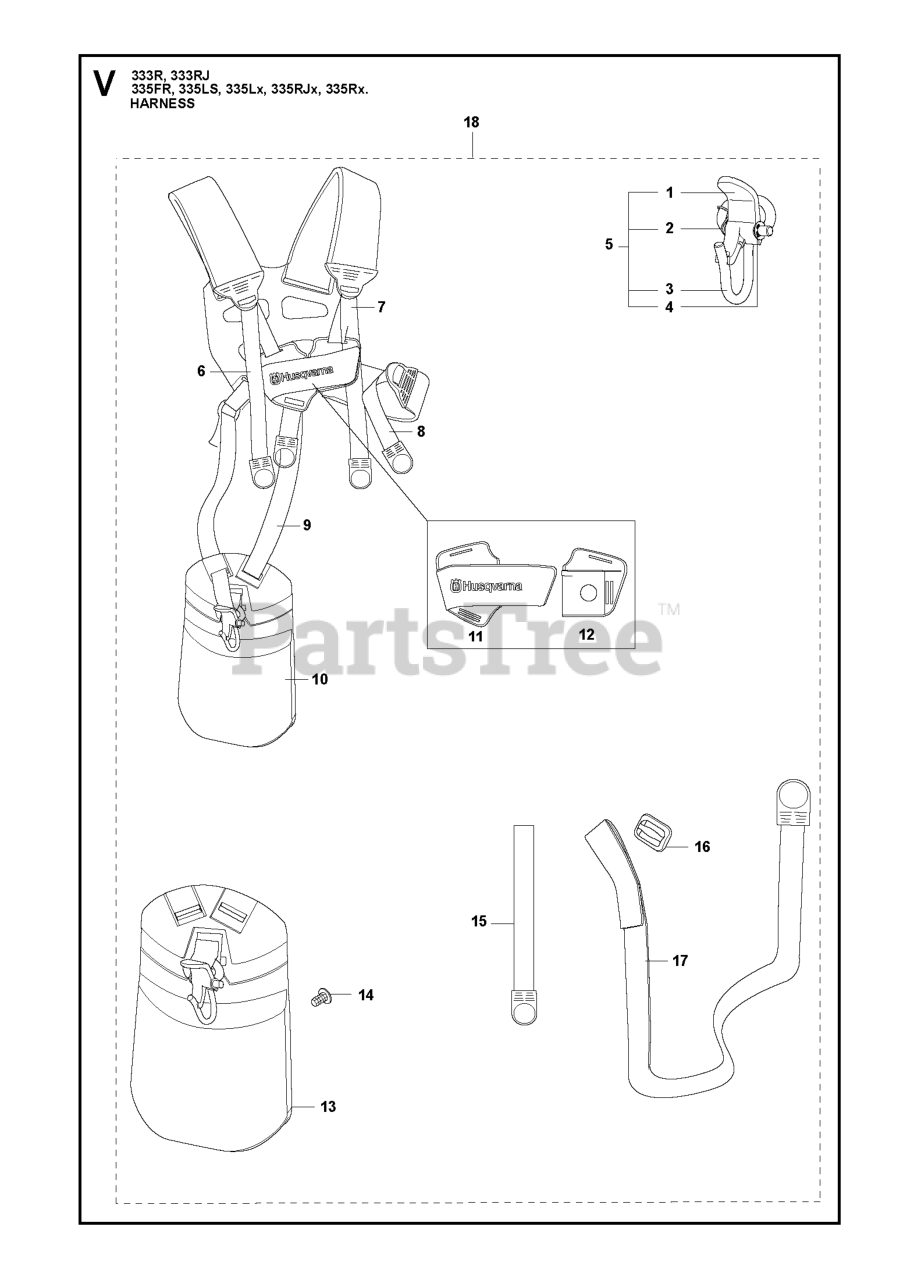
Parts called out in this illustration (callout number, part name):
1	CATCH *
2	SPRING
3	HOOK
11	FRONT PIECE
12	FRONT PIECE
16	RP CLIP
18	Harness
18	Duo Balance Harness
